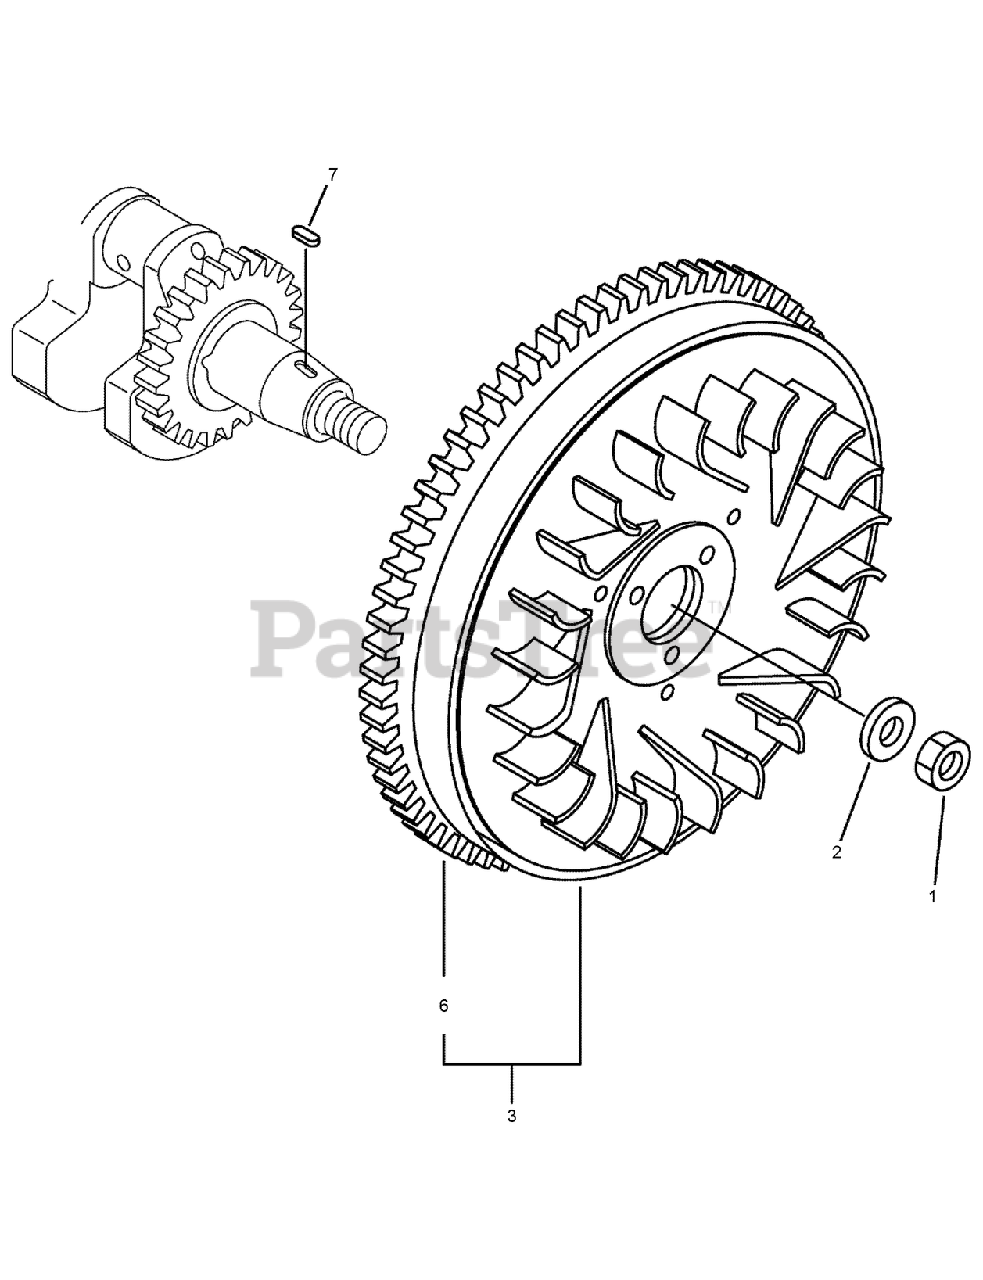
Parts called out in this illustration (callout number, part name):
1	NUT-WHEEL
2	WASHER-FLYWHEEL
3	FLYWHEEL ASM
6	GEAR-RING
